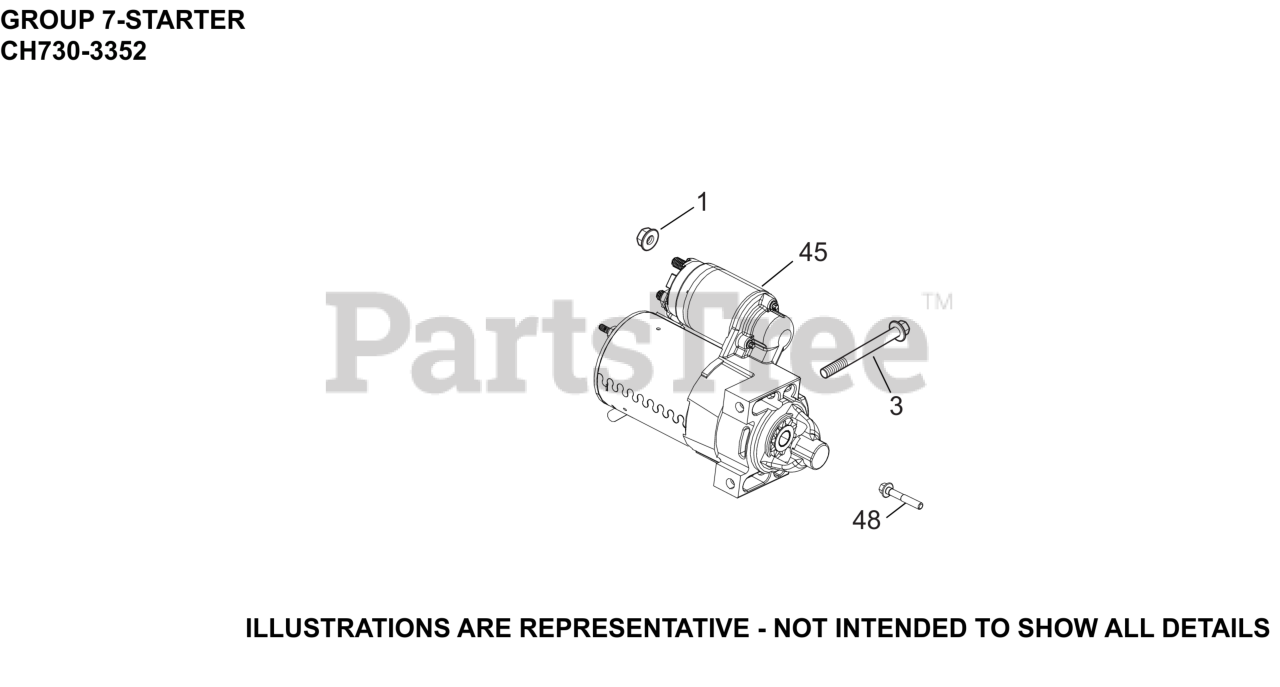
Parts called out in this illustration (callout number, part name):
1	NUT, FLG M8X1.25
3	SCREW, FLG M8X1.25X80
45	STARTER, SOLENOID SHIFT (25 098 09-S)
48	SCREW, HEX FLANGE
